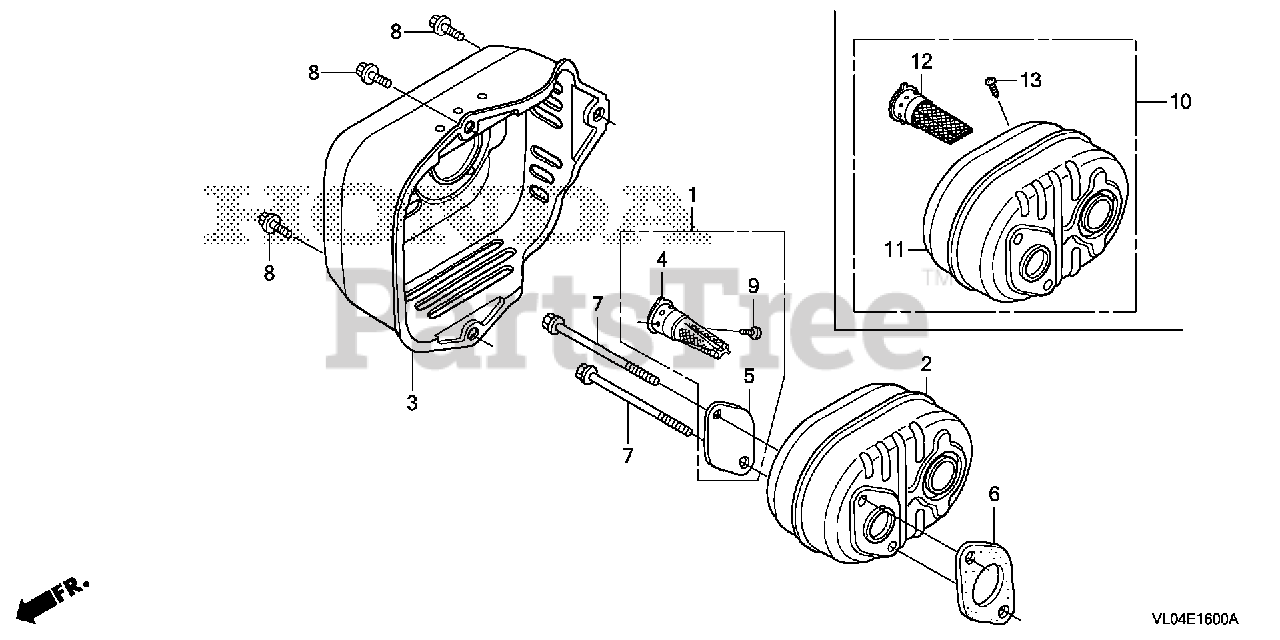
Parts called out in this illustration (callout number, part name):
1	ARRESTER KIT, SPARK
3	PROTECTOR, MUFFLER
4	ARRESTER, SPARK
5	PLATE, ARRESTER NUMBER
6	GASKET, MUFFLER
7	BOLT, FLANGE (6X79) (CT200)
8	BOLT, FLANGE (6X12) (CT200)
9	SCREW, TAPPING (4X6)
